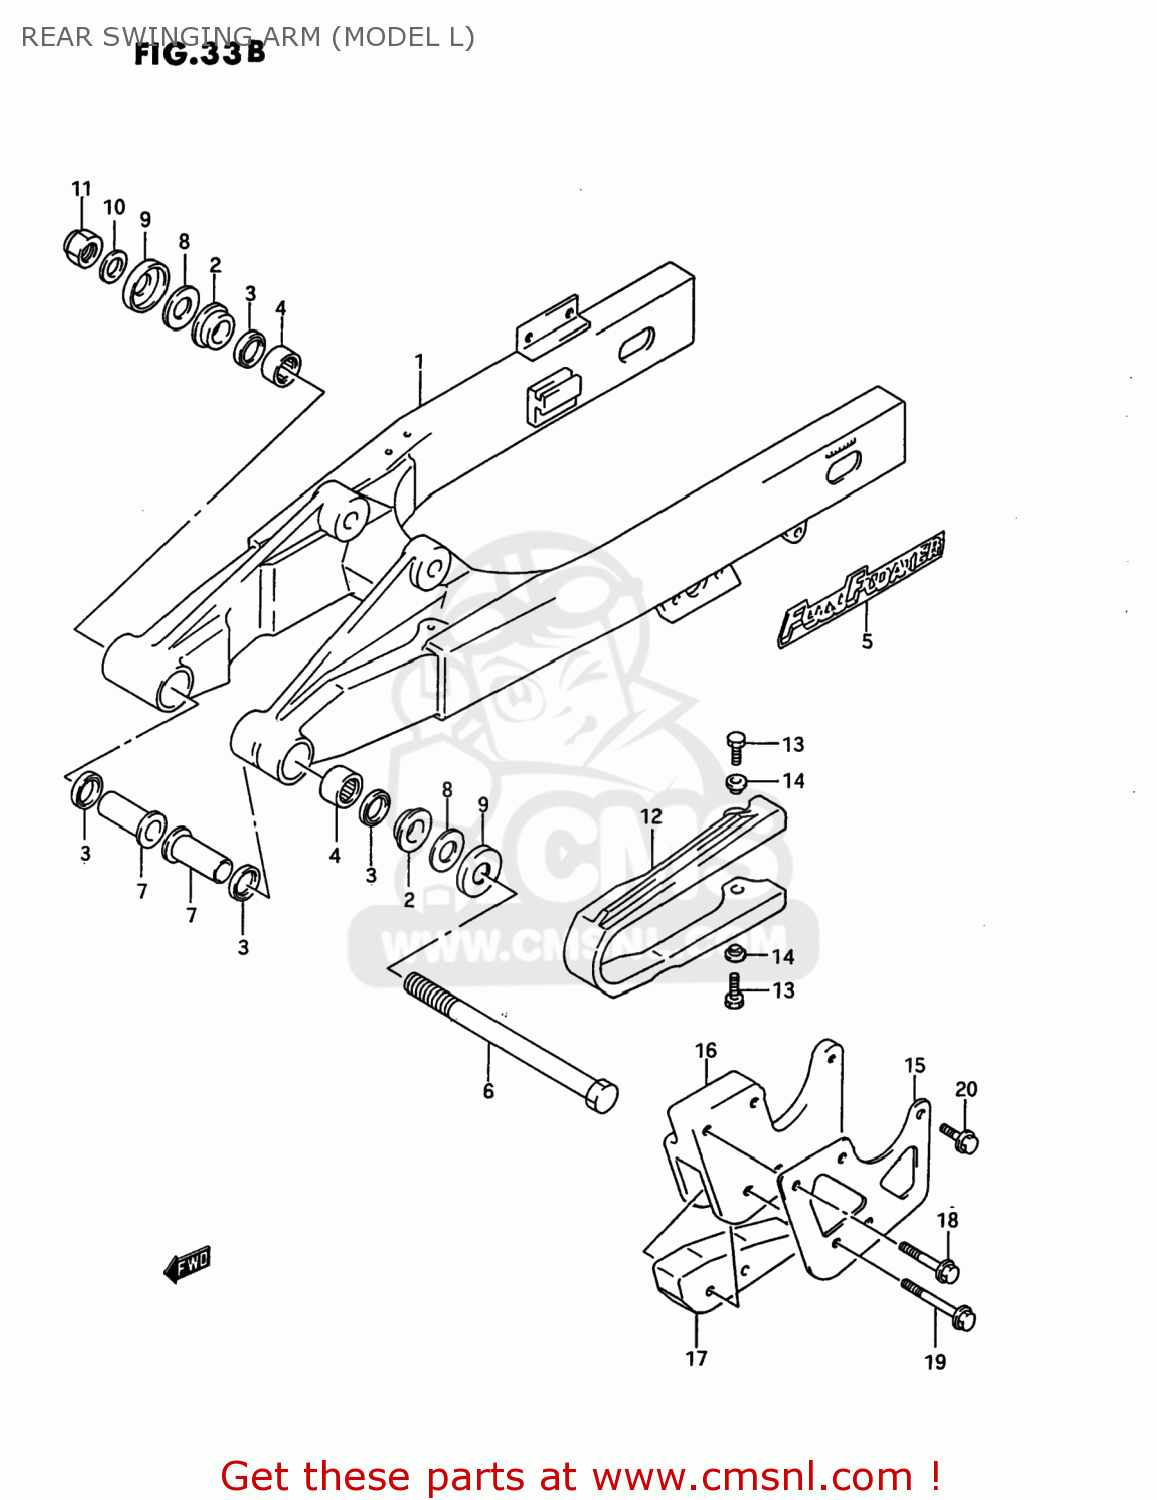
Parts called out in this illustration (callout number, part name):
1	SWING ARM ASSEMBLY,REAR
2	BUSHING,SWGARM PIVOT
3	SEAL,OIL(17X24X3)
4	ROLLER BEARING (17X24X25)
5	LABEL
6	SHAFT,RR SWINGINGARM PIVOT
7	SPACER,RR SWGARM PIVOT
8	WASHER
9	COVER,REAR SWING ARM DUST
10	WASHER
11	NUT 12MM
12	BUFFER,CHAIN TOUCH DEFENSE
13	BOLT
14	WASHER
15	PLATE,GUIDE CHAIN OUTER
16	GUIDE,CHAIN
17	DEFENSE,CHAIN GUIDE
18	BOLT
19	BOLT
20	BOLT
